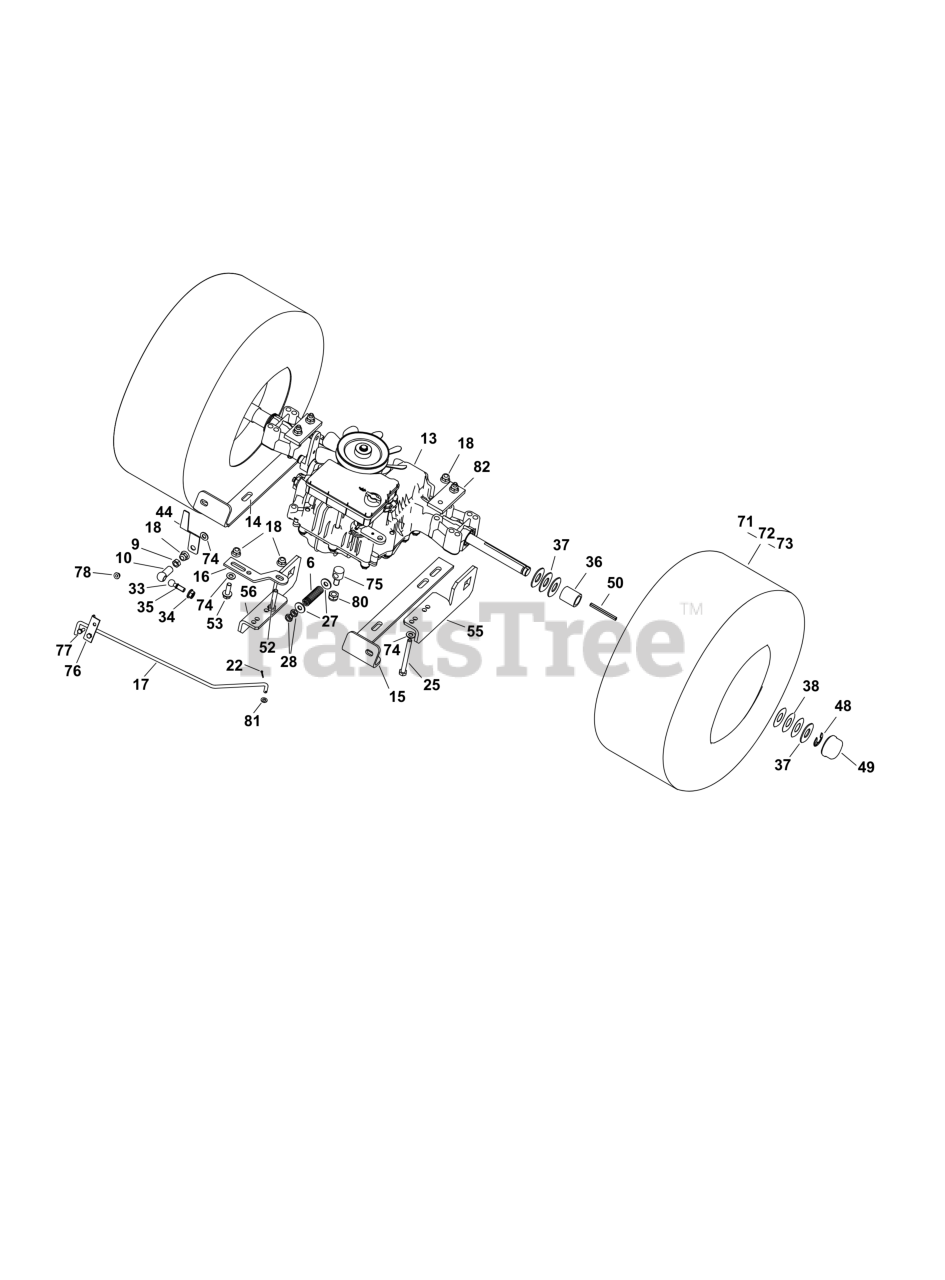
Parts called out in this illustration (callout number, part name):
13	TRANSMISSION
17	ROD, Bypass
48	RING, Locking
71	WHEEL, Rear
